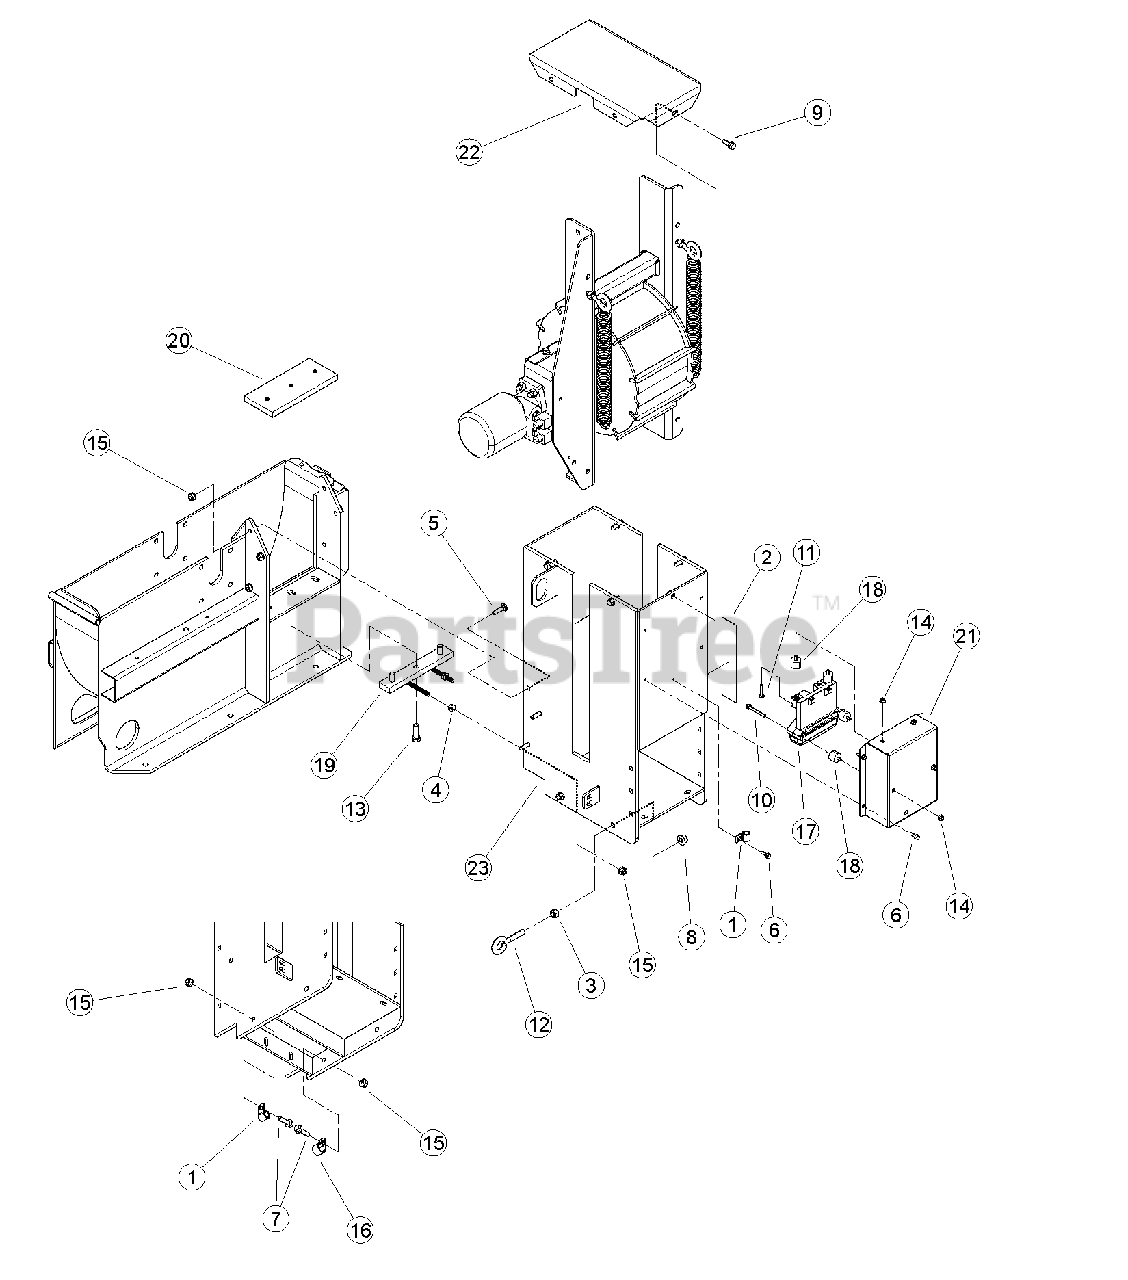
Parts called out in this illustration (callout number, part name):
1	CLAMP, 9/16 COATED
2	DECAL, CHIPPER ENGAGEMENT
3	NUT, 1/2 HEX NC ZP
4	NUT, 3/8" SERRATED FLANGE NC ZP
5	BOLT, 3/8 X 1-1/2" GR5 CRG NC ZP
6	BOLT, 1/4-20 X 3/4 HWH GR5 CZP
7	BOLT, 3/8 X 1-1/4 FLANGE NC
8	NUT, 1/2-13 NYLOCK FLANGE
9	BOLT, 3/8 X 1 FLANGE NC
10	BOLT, 1/4 X 2-1/4 FLANGE NC
11	BOLT, 1/4-20 X 1-1/4 GR5 HHCS MAGNI 565 SILVER
12	EYEBOLT, 1/2 X 2" ZP
13	BOLT, 1/2 X 1-1/2 GR8 NC ZP HEX HD
14	NUT, 1/4-20 NYLOCK-FLANGE
15	NUT, 3/8-16 NYLOCK FLANGE
16	CLAMP, 1" COATED METAL
17	CONTROLLER, PLUS 1 CHIPPER
18	BUMPER, 1" OD W/1/4" STUD
19	WELDMENT, BLOCK ADJUSTOR
20	PLATE, CHIPPER BOTTOM
21	ENCLOSURE, PLUS 1 MOUNT
22	WELDMENT, TOP ROLLER COVER
23	WELDMENT, ROLLER SUPPORT
